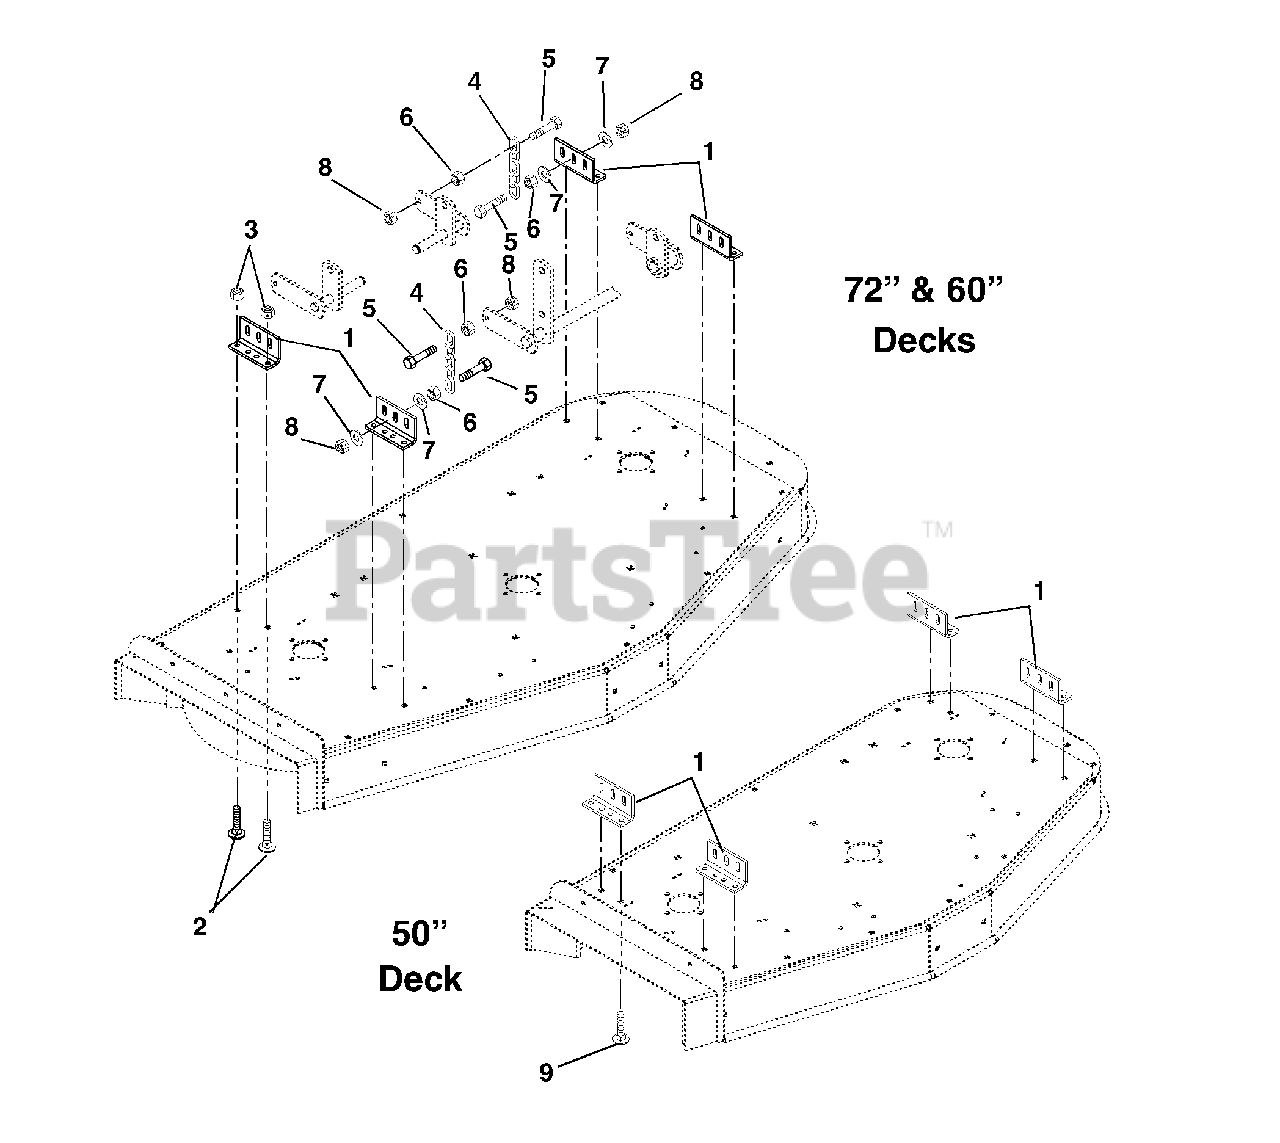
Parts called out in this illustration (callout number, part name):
1	Bracket, Mower Mounting
2	Bolt-Round Head Square Neck .38-16 x 1.25 Grade 2
3	Nut-Locking-Nylon .38-16
4	Chain, Link
5	Bolt-Hex .38-16 x 1.50 Grade 5
6	Nut-Hex .38-16
7	Washer-Flat-Steel .406 x .812 x .065
8	Nut-Locking-Center .38-16
9	Bolt-Round Head Square Neck .38-16 x 1.50 Grade 2
